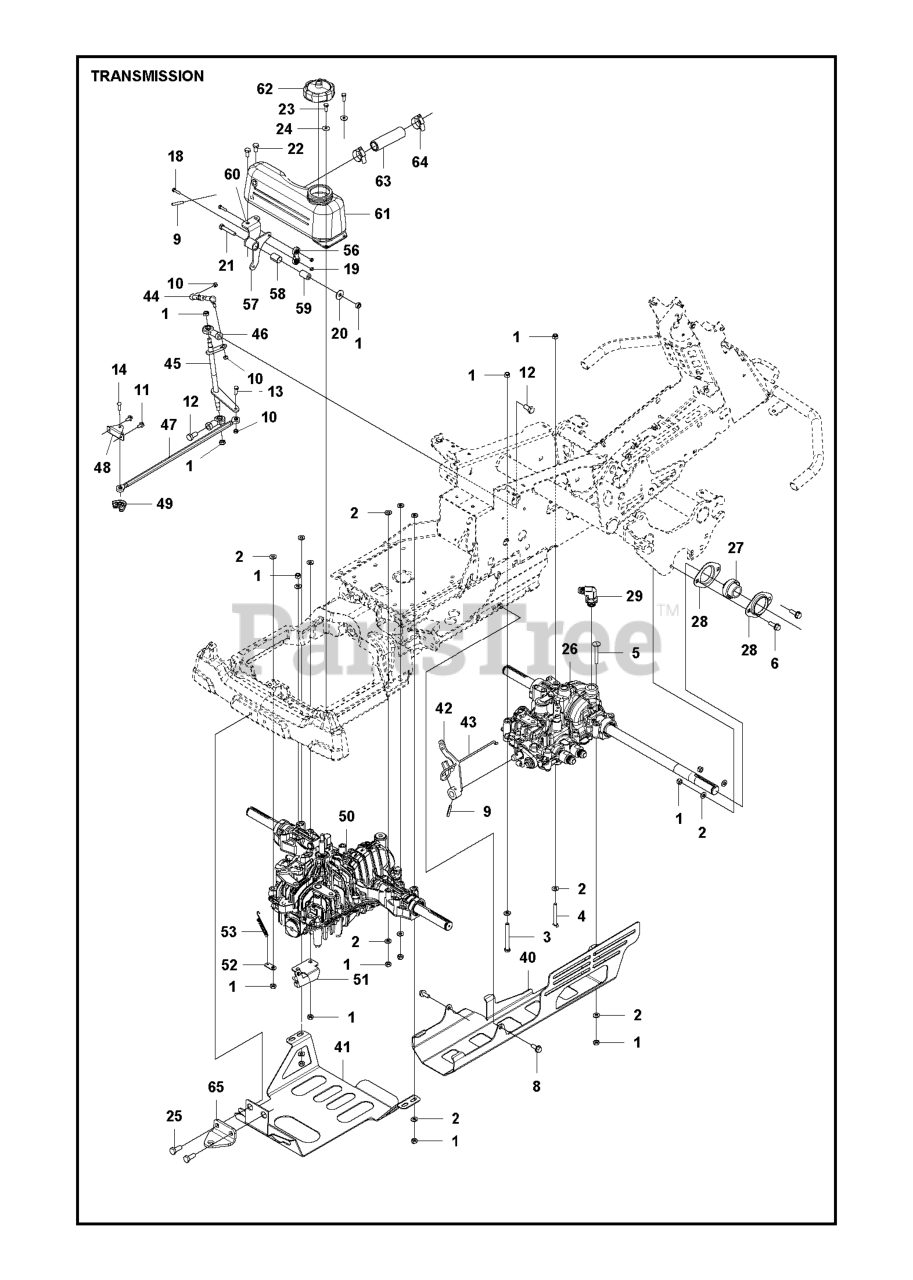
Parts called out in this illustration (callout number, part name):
1	LOCKNUT M8
2	WASHER BRB 8.4X17
6	BOLT
10	LOCKNUT M6
11	SCREW EHHFM
13	SCREW EHHM
18	SCREW M6S 5X20
19	LOCKNUT M5
21	SCREW
22	BOLT - M8X16
23	SCREW
24	WASHER - 26X6.5X1.6
25	Screw M10x25
28	BEARING HOUSING
44	ADJUSTING ROD
61	EXPANSION TANK K664
